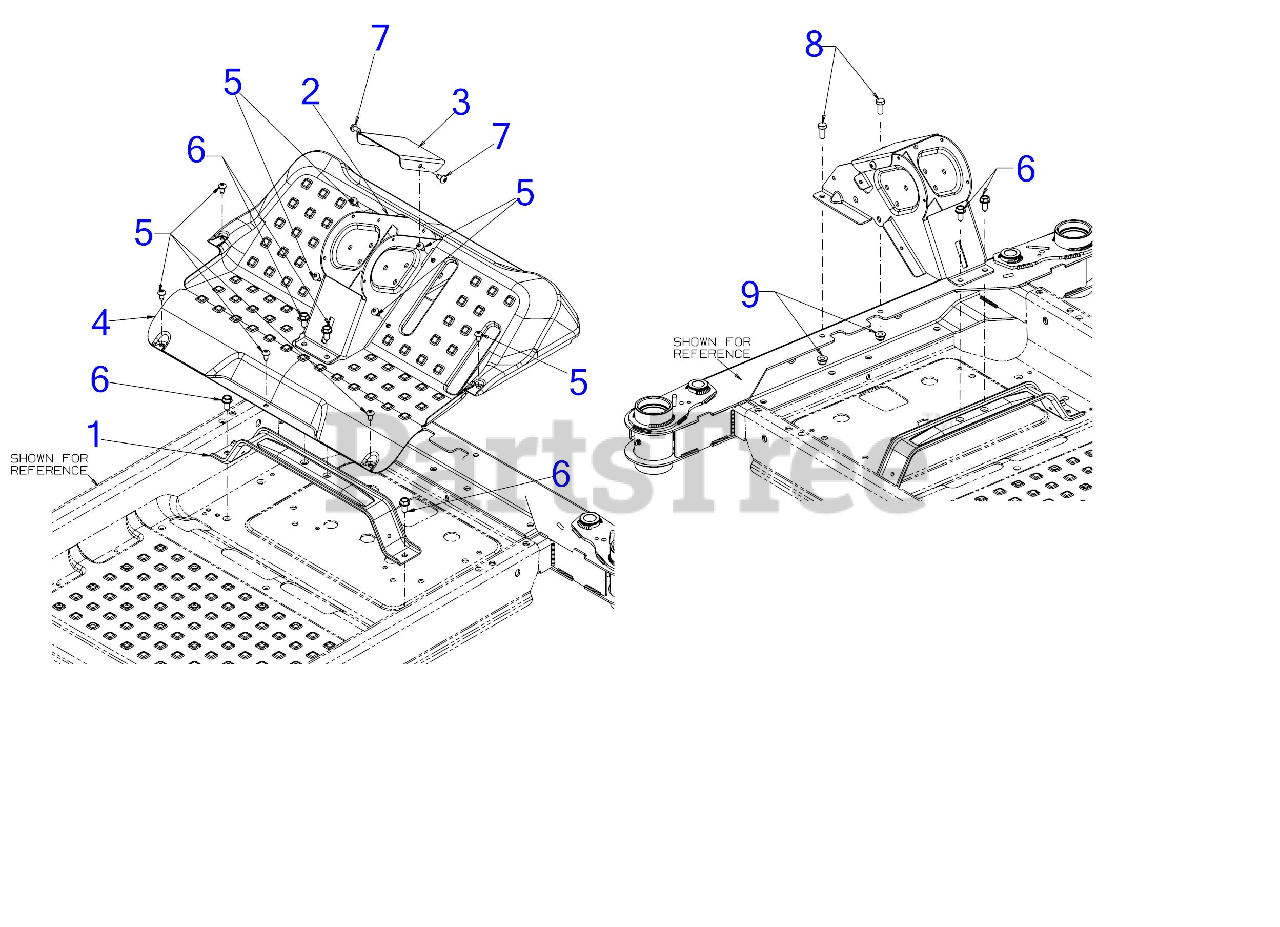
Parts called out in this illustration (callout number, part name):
5	SCREW 1/4-20 x .500
6	SCREW 5/16-18 x .750
7	SCREW 1/4-20 x .5
8	SCREW 5/16-18 x .75 GR5
9	FLANGE LOCK NUT 5/16-18
